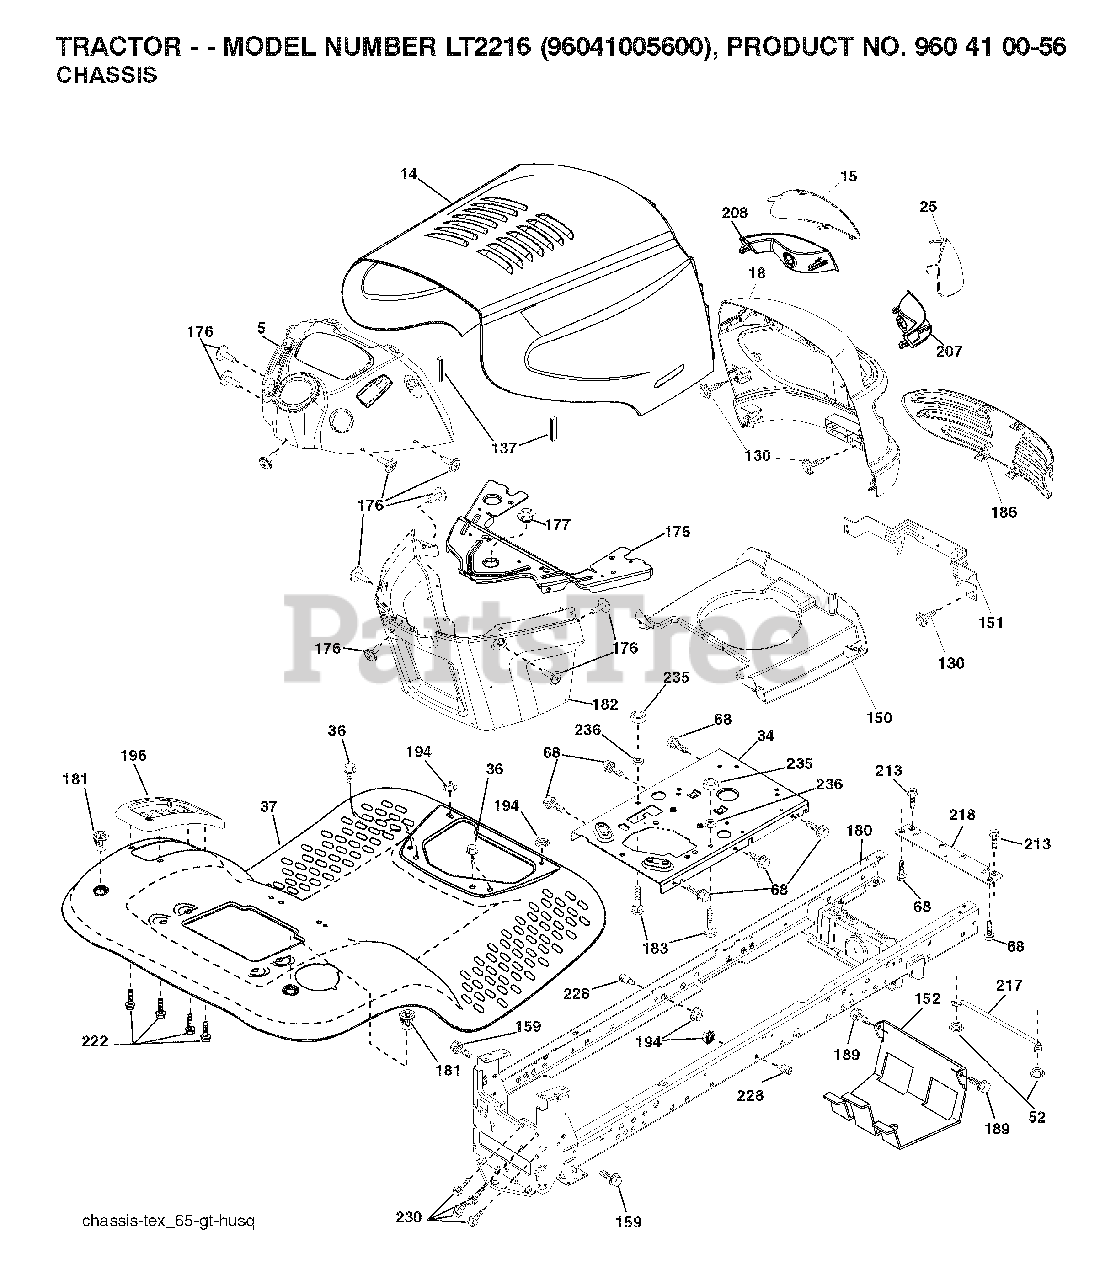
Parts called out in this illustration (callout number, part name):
5	DASH.P/L.TEX.CBL.CL.N/CHK.BLAC
34	PLATE.ENGINE.WELDED.CHASSIS
36	SCREW 5/16"
52	LOCKNUT
130	SCREW
137	BUMPER.HOOD.LARGE.1.75"
151	BRACKET PIVOT
152	SHIELD BROWNING
159	SCREW, 3/8-16X3/4
175	CROSSMEMBER.LT
176	SCREW.#10-24X5/8.RN.QU
177	BUSHING STEERING
180	CHASSIS
181	FEND/FTRST.PCH.CPH.NFW
182	DASH.LOWER.LT.CCS
183	BOLT.5/16-18X1-1/4 FULL.THREAD
189	SCREW
194	NUT LOCK HEX FLANGE 5/16-18
196	CONSOLE.ASM.DECK.LIFT.TLT.BLAC
207	BEZEL GRILL RH
208	BEZEL GRILL LH
213	BOLT
217	ROD.PIVOT.HOOD
218	X-PIECE.HOOD.STOP.NON/
222	SCREW.1/4-20X5/8
228	STUD.FASTNER.W/ANTI-ROTATE
230	SHOULDER BOLT 5/16-18TT
235	SPACER FENDER
236	NUT.CENTERLOCK.5/16-
